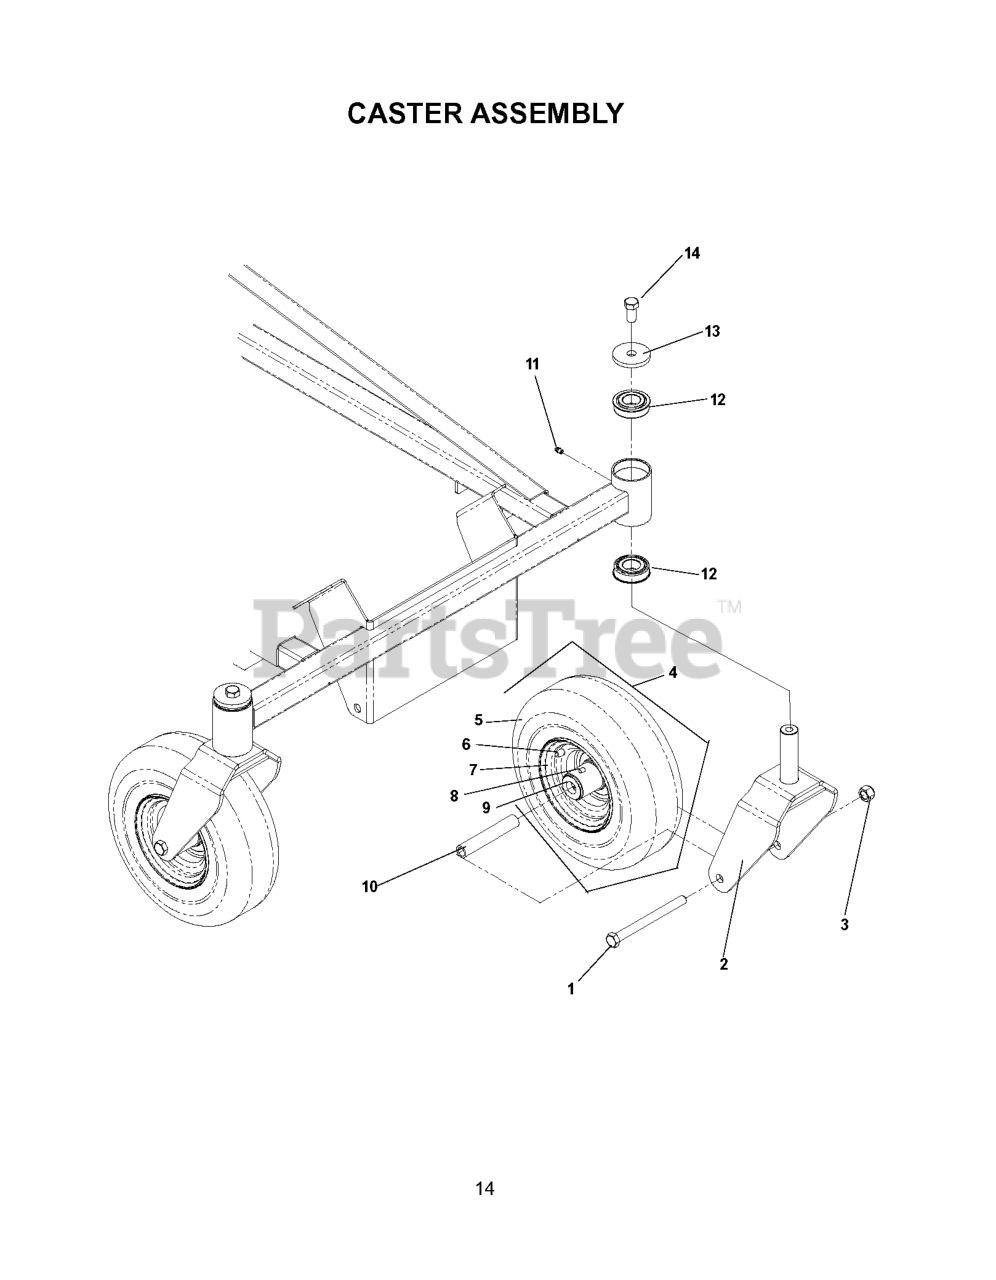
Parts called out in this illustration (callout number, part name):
1	HCS 1/2C X 5 1/2
2	CASTER YOKE - PAINTED
3	NUT 1/2-13 HEX NYLOC ZD
4	TIRE/WHEEL.CASTER
5	TIRE - CASTER
6	VALVE STEM TR-412
8	ZERK
9	BEARING RETAINER
12	BEARING FLANGED
13	HEAVY WASHER
14	HHCS 1/2-13 X 1
